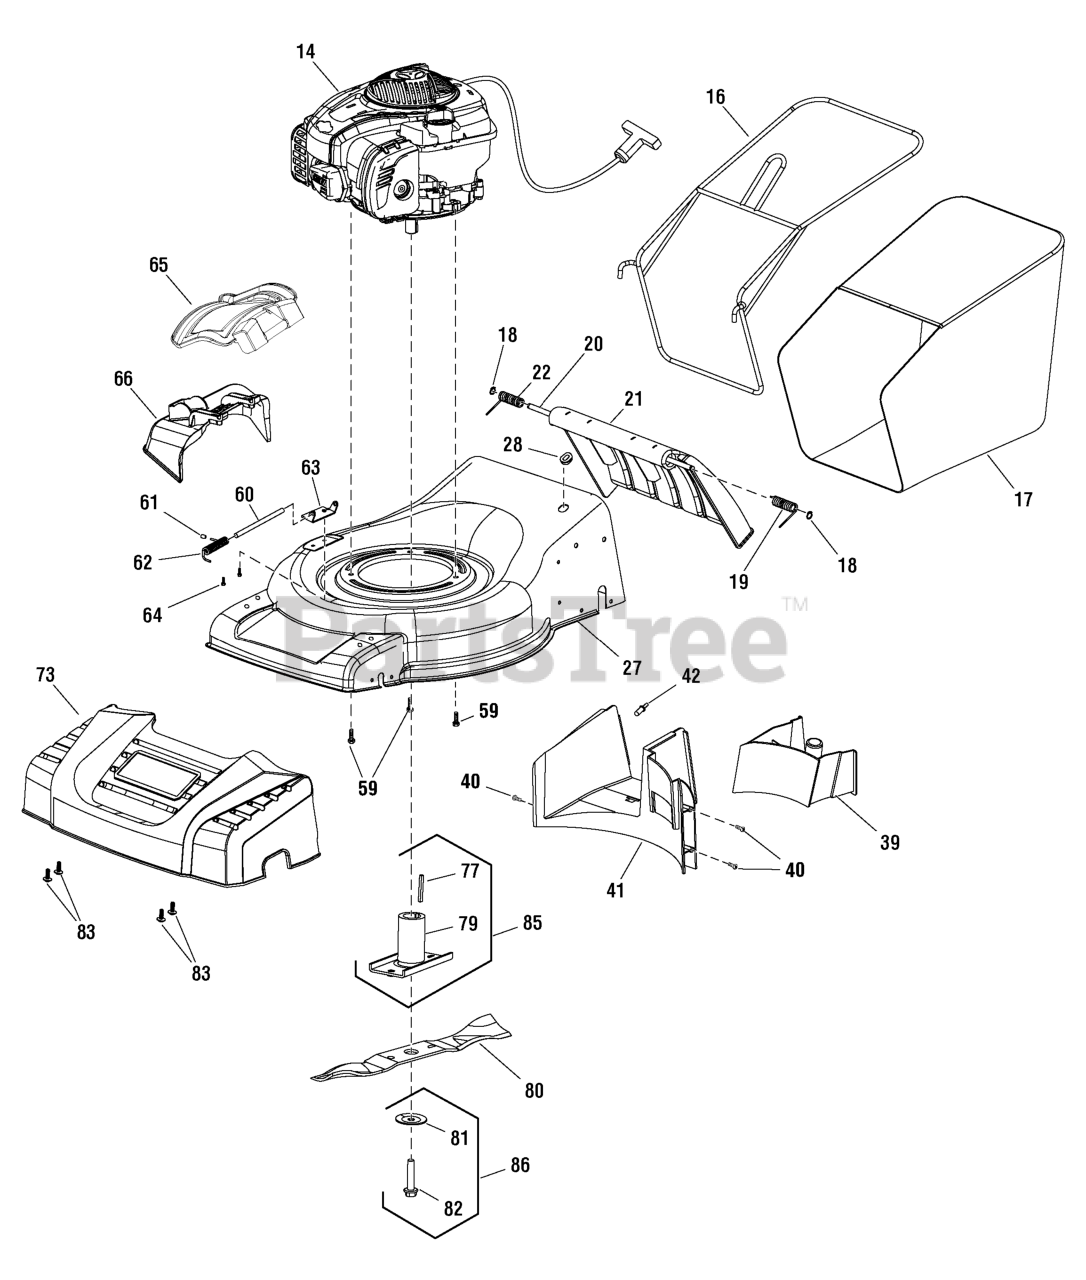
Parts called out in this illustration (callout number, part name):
14	* ENGINE, Briggs & Stratton 675EX Series
16	FRAME, Grass Bag
17	BAG, Grass
18	CIRCLIP
19	SPRING, Left
21	REAR FLAP
22	SPRING, Right
28	GROMMET
39	MULCH PLUG
40	SCREW, With Washer, ST4.8 x 13
41	BAFFLE, Rear
59	BOLT, Self Tapping
61	CAP, Spring
62	SPRING, Torsion
63	BRACKET, Deflector
64	BOLT, M6 x 10
65	COVER, Mulching
66	CHUTE, Side Discharge
73	FRONT COVER
79	ADAPTER, Blade
81	WASHER, Cone
82	BOLT, Blade, 3/8-24 UNF
83	SCREW, With Washer, ST4.8 x 13
85	KIT, Blade Adapter
86	KIT, Hardware, Blade Bolt
